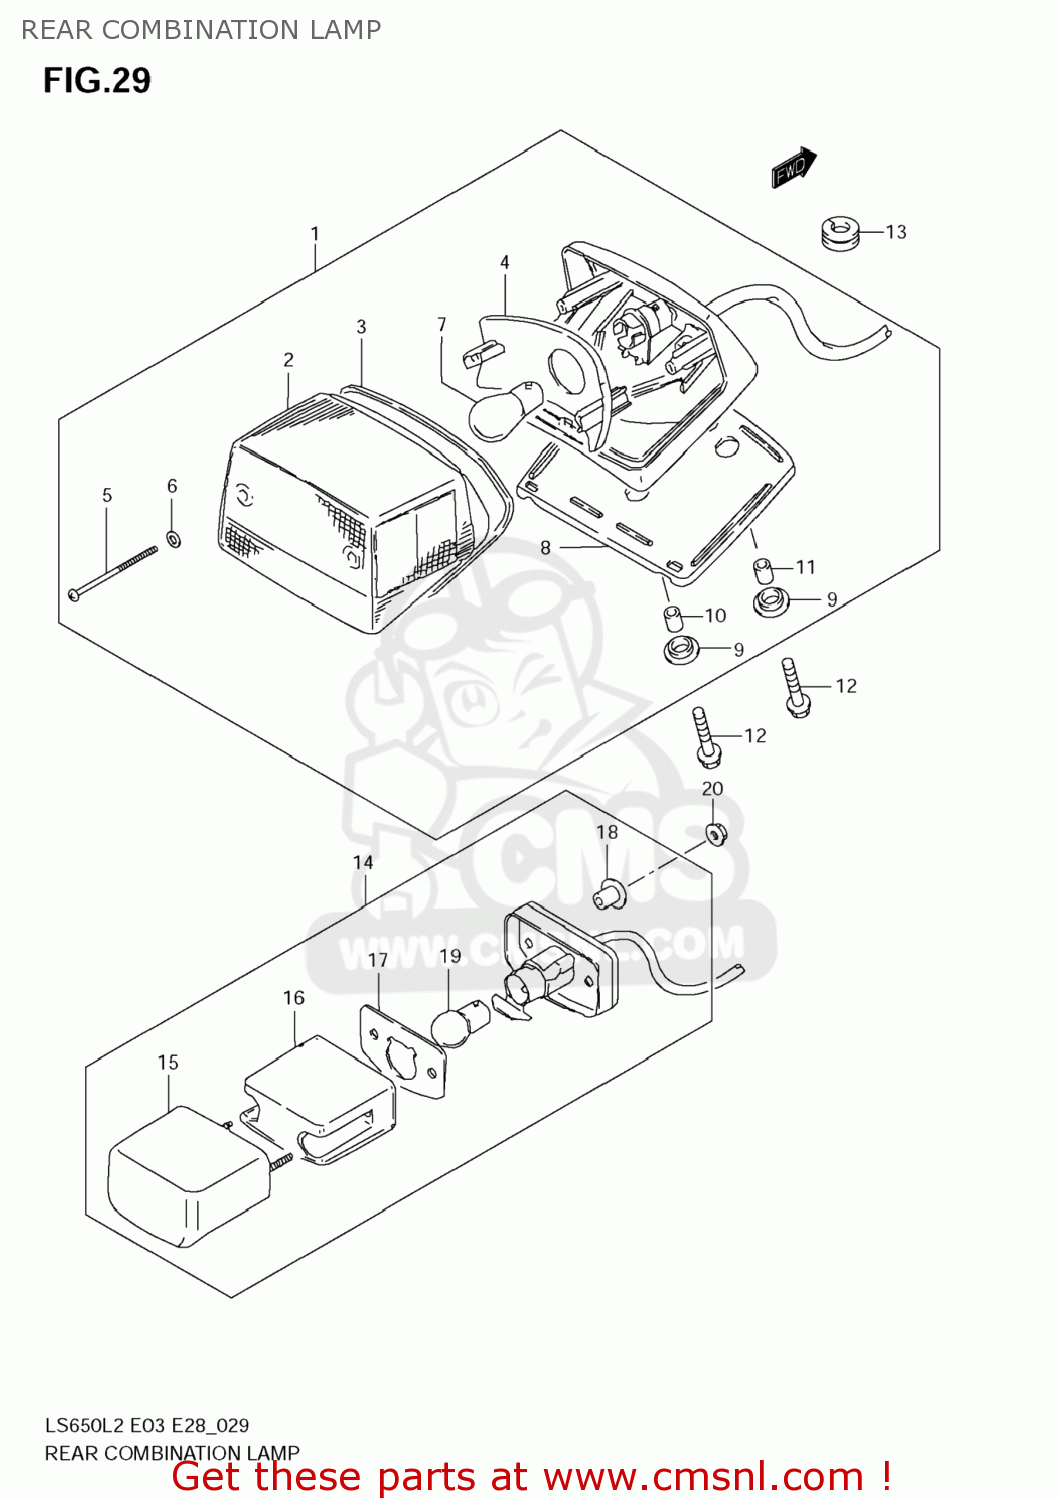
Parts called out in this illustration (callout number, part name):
1	LAMP ASSY,RR COMBINATION
2	LENS
3	GASKET (NAS)
4	REFLECTOR
5	SCREW
6	GASKET (NAS)
7	BULB(12V21/5W,BF141-49642A)
8	CUSHION
9	CUSHION
10	SPACER
11	SPACER
12	BOLT(6X25)
13	GROMMET
14	LAMP ASSY,LICENSE
15	COVER,LENS
16	LENS
17	GASKET,LICENSE LAMP (NAS)
18	SPACER
19	BULB(12V5W,BF150-40160A)
20	NUT
